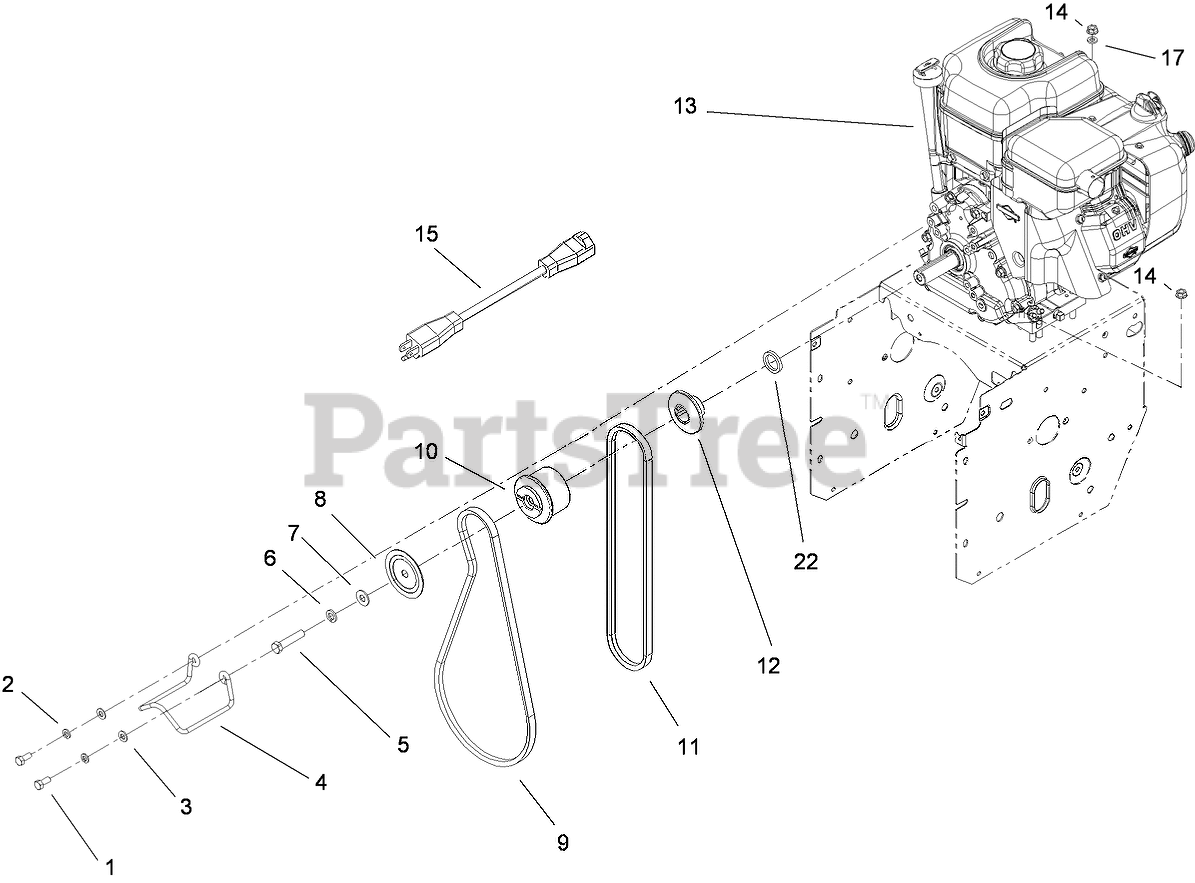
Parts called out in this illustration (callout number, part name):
1	SCREW-HH
2	WASHER-LOCK
3	WASHER-PLAIN
4	GUIDE-BELT
5	SCREW-HH
6	WASHER-LOCK
7	WASHER-FLAT
8	SHEAVE-HALF, IMPELLER
9	BELT-V
10	PULLEY-ENGINE, CENTER
11	V BELT-TRACTION
12	SHEAVE-HALF, TRACTION
14	NUT-HF
15	CORD-EXTENSION
17	WASHER-FLAT
22	SPACER-HARDENED
